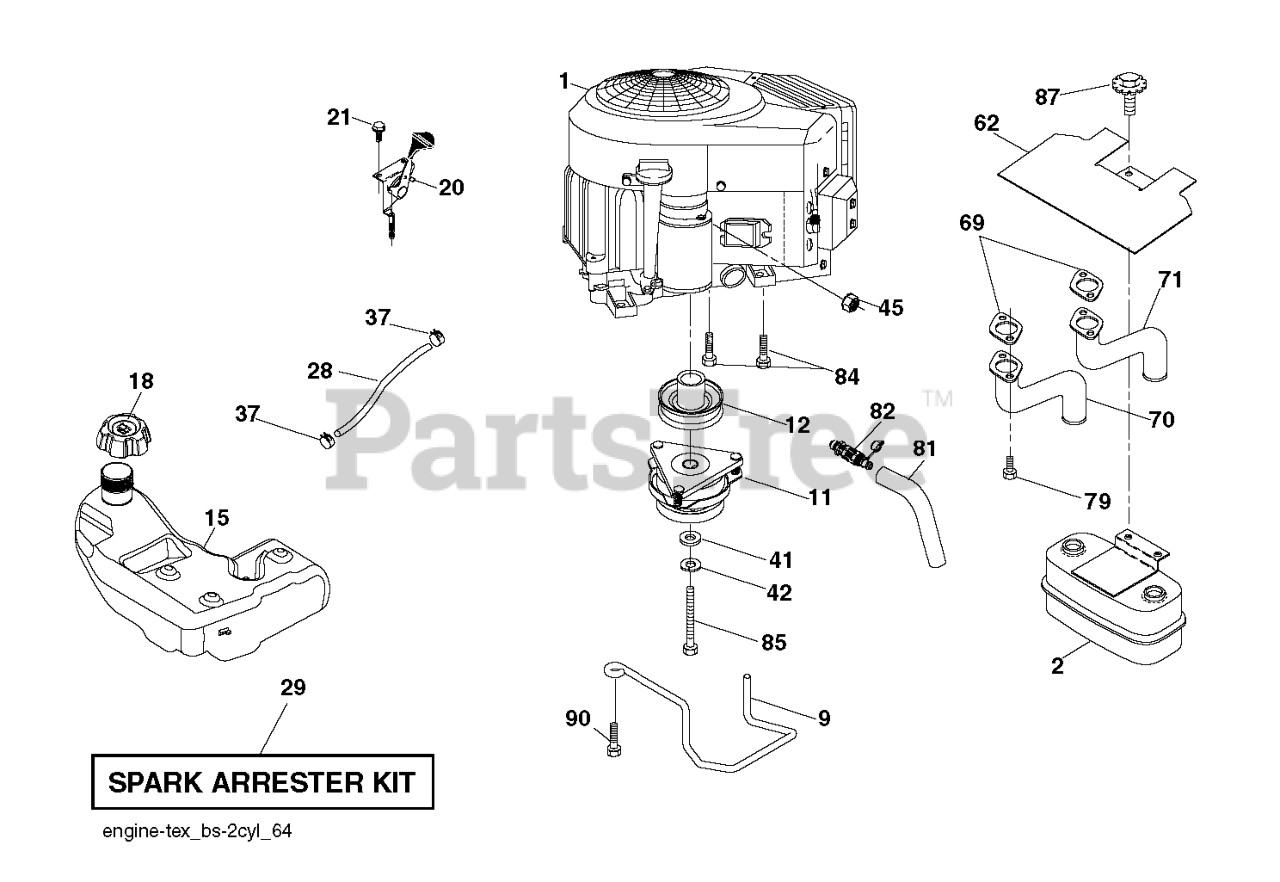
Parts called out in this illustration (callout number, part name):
2	MUFFLER.TWIN.CYL.LOW.TONE
9	KEEPER.BELT.ENGINE.4.2
11	CLUTCH.ELECTRIC.LT.48"*
12	PULLEY.ENGINE.TUFFTORQ
15	RP_TANK.ASSY.3.GAL.EPA
18	CAP.ASM.FL.RITCH.3"E10.SYM.498
20	CONTROL.TH/CK.COBRA.B&S.TWN.BK
21	SCREW.#10 X 0.750.BOS
28	LINE.FUEL.64"REAR.EMIS
29	KIT.SPARK ARRESTOR 794945 B&S
37	HOSE CLAMP
42	LOCKWASHER
45	NUT
62	SHIELD.HEAT.MUFFLER
69	GASKET.MUFFLER
70	EXHAUST.TUBE.LH.BS/TWIN
71	EXHAUST.TUBE.RH.B&S.TWIN.INTEK
79	SCREW.SOCKET.HEAD.5/16-18
81	TUBE, DRAIN OIL ASM.
82	VALUE.OIL.DRAIN
84	SCREW.3/8-16
85	BOLT HEX 7/16-20X4-1/4"
87	BOLT.5/16-18UNCX3/4 W/SEMS.BLK
90	SCREW 3/8-16X1
